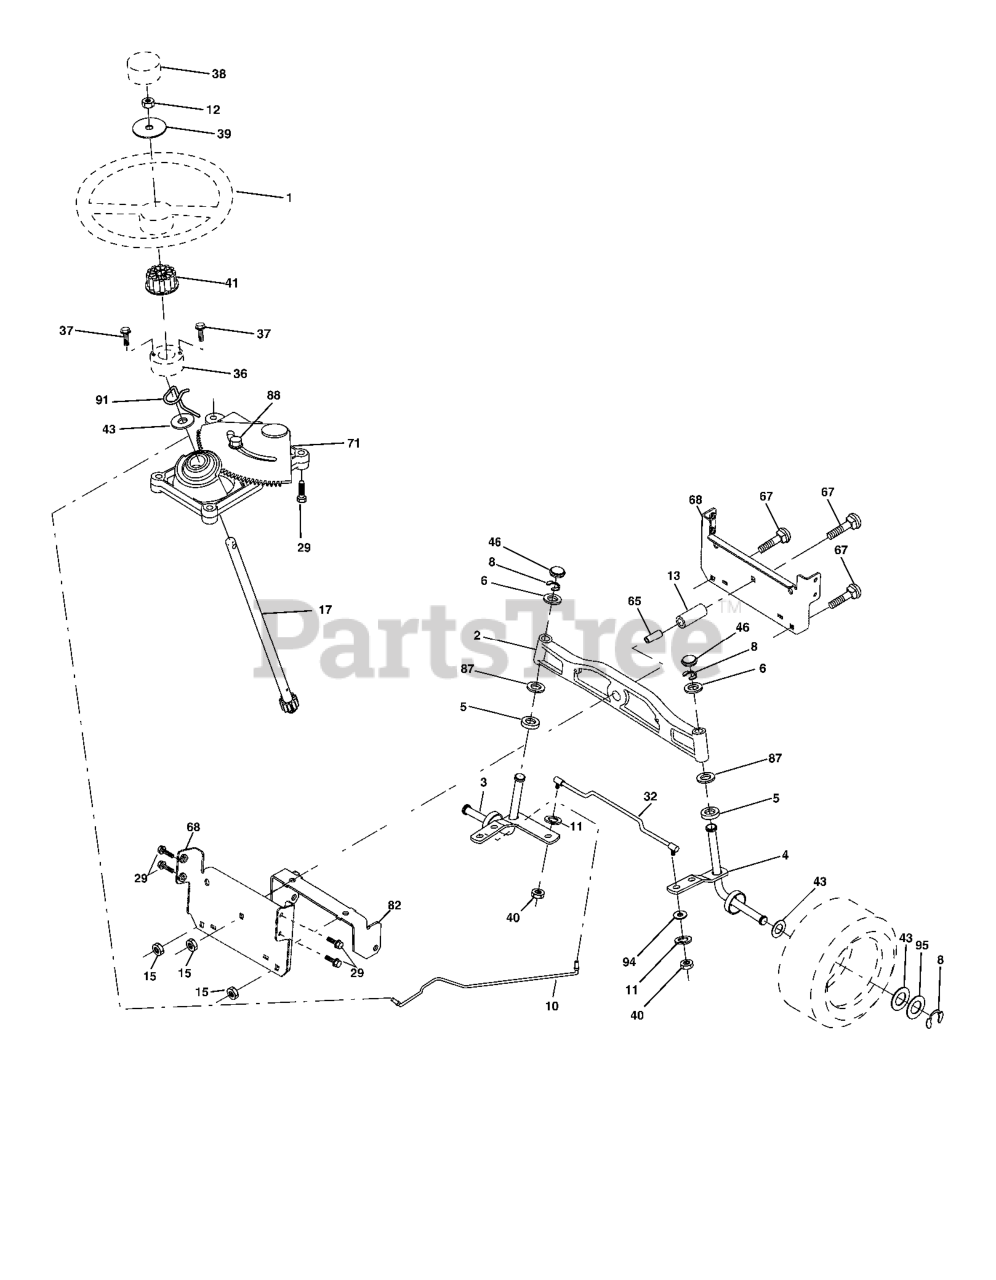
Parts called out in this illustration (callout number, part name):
1	STEERING WHEEL
2	AXLE ASSY FRONT
3	SPINDLE.ASM.LH.15"TIRES
4	SPINDLE.ASM.RH.15"TIRES
5	THRUST WASHER
6	WASHER
8	RING CLIP
10	DRAGLINK.15".TIRES.2001
11	WASHER, LOCK 3/8
12	NUT.HEX.1/2-20
13	TUBE, PIVOT AXLE
15	NUT
17	SHAFT ASM STRG
29	SCREW, 3/8-16X3/4
32	ROD TIE BALL J WSL
34	WASHER.LOCK.HVY.HLCL.SPR.5/16
36	BUSHING, STRG. BLK
37	SCREW.TT.#10-32X.5.3/8.FLANGE
38	CAP.WHEEL.STEERING.GREY
39	WASHER 9/16"ID, 2 3/8"OD
40	NUT CROWNLOCK 3/8-24
41	STEERING WHEEL ADAPTOR
43	WASHER
46	CAP.SPINDLE.BLACK
65	SPACER BRACE AXLE
67	BOLT CARRIAGE
68	BRACE.AXLE.15"TIRES
71	STEERING ASM
82	BRACKET
87	WASHER, FLAT .781 X 1 1/2"
88	BOLT, SHOULDER 7/16-20
91	CLIP.STEERING
94	WASHER.5/16.FLAT.STE.STD.
95	WASHER.HARDENED
